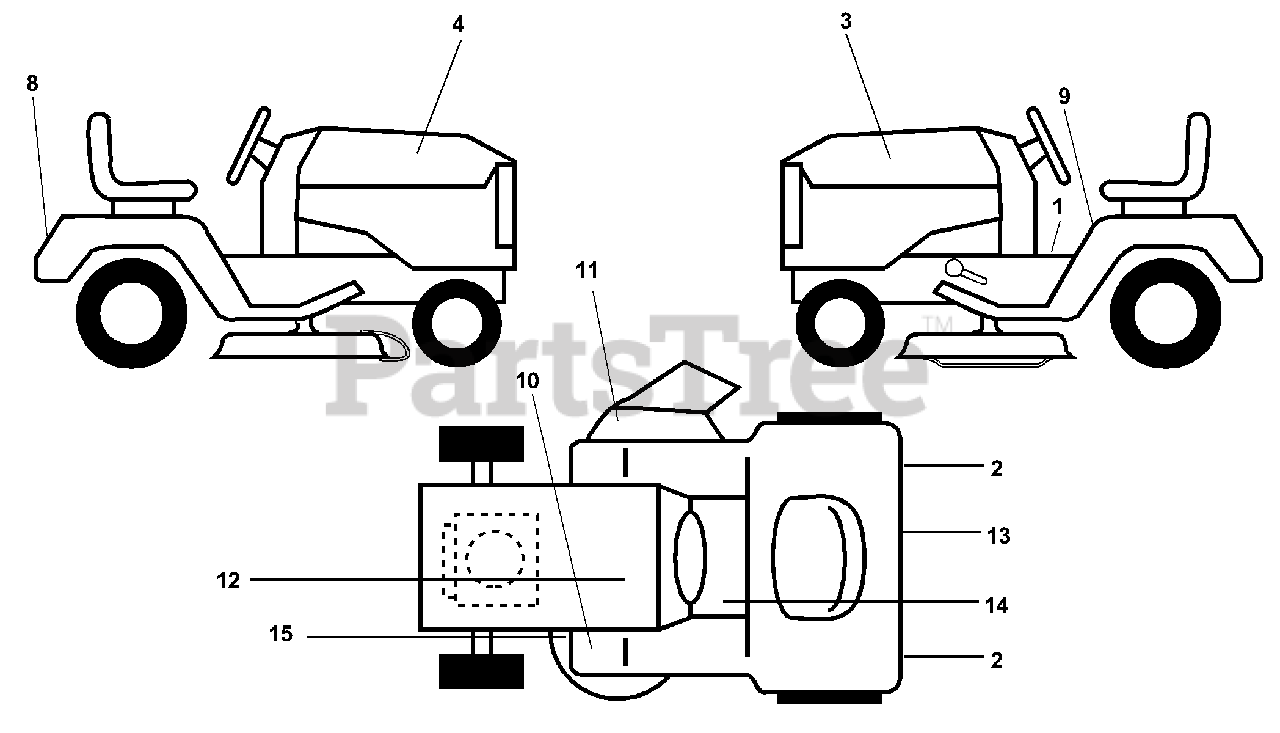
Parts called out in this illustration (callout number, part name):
1	Decal Instruction Dash Eng/fr
2	Reflector Tail Light Red/amber
3	Decal Hood LH Husq P/L YTH180
4	Decal Hood RH Husq P/L YTH180
8	Decal Fender Logo Husq
9	Decal Caution Fender Eng/fr
10	Decal Clutch/brake Eng/fr
11	Decal Warning Multi-Language
12	Decal Bat Dan/Poi P/L Sym WPN
13	Decal Drawbar CNTRL MVT HYD LT
14	Decal SDL COLD START HYD E/F
15	Decal V-Belt Schematic 44" 46" 50" Vented
